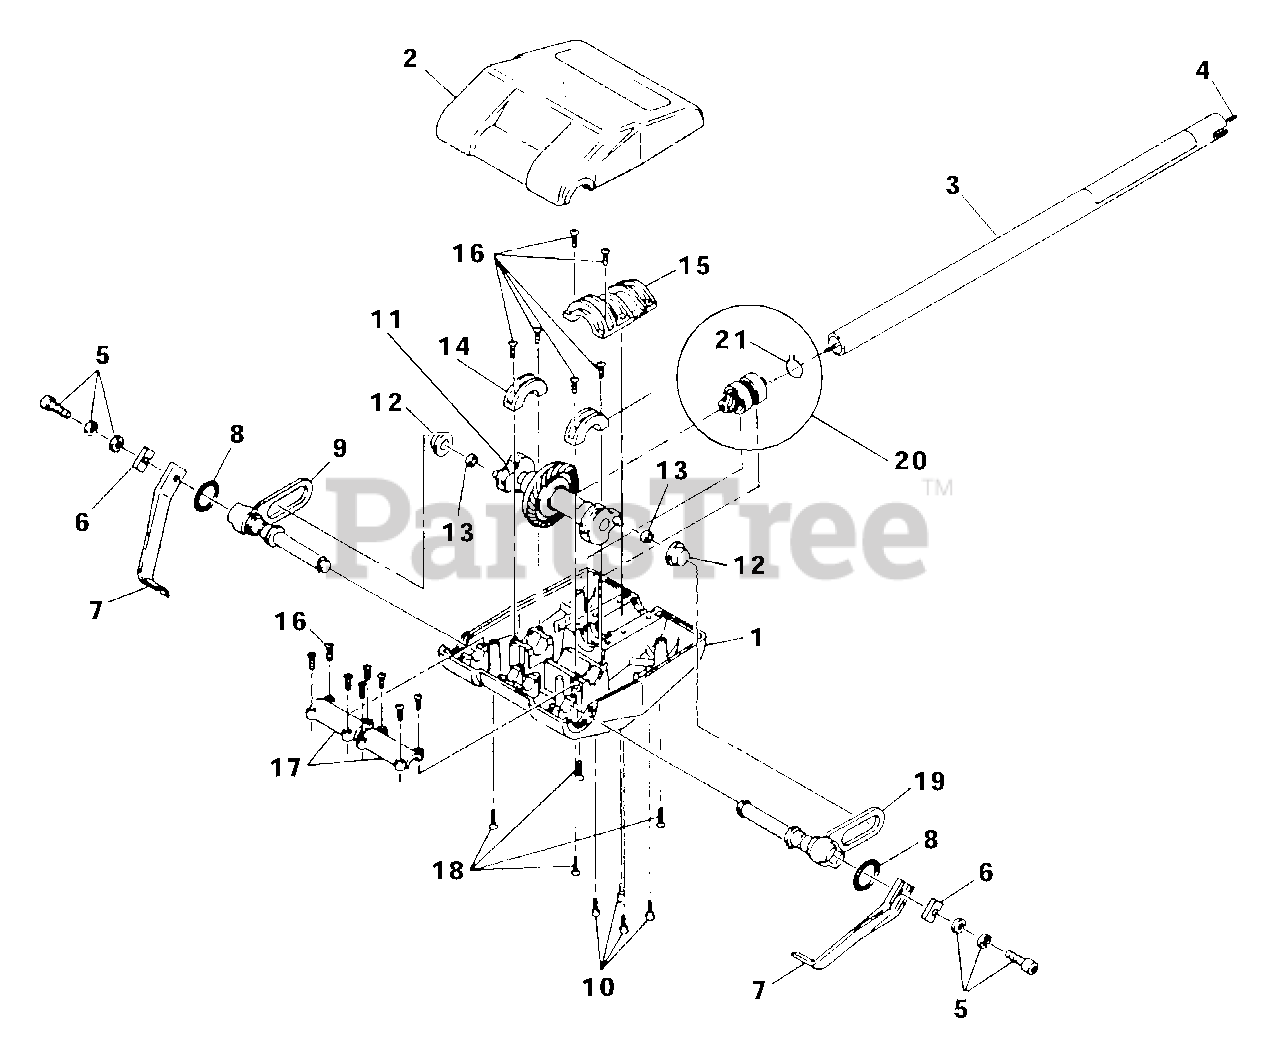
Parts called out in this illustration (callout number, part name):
1	LOWER COVER
2	UPPER HOUSING
3	DRIVESHAFT HOUSING
4	FLEX CABLE
5	BOLT-Sems (1/4 - 28 x 1")
6	SUPPORT-Tine
8	"O" RING
9	ROCKER ARM (L.H.)
10	SCREW, Thread Form (10-24 x 3/4")
11	CRANK ASSY.
12	FLOATING BUSHING
13	WASHER
14	CRANKSHAFT CLAMP
15	SHAFT CLAMP
16	SCREW, Thread Form (10-24 x 3/4")
17	SHAFT CLAMP
18	SCREW (8-16 x 1")
19	ROCKER ARM (R.H.)
20	PINNON GEAR & BEARING
21	SNAP RING
